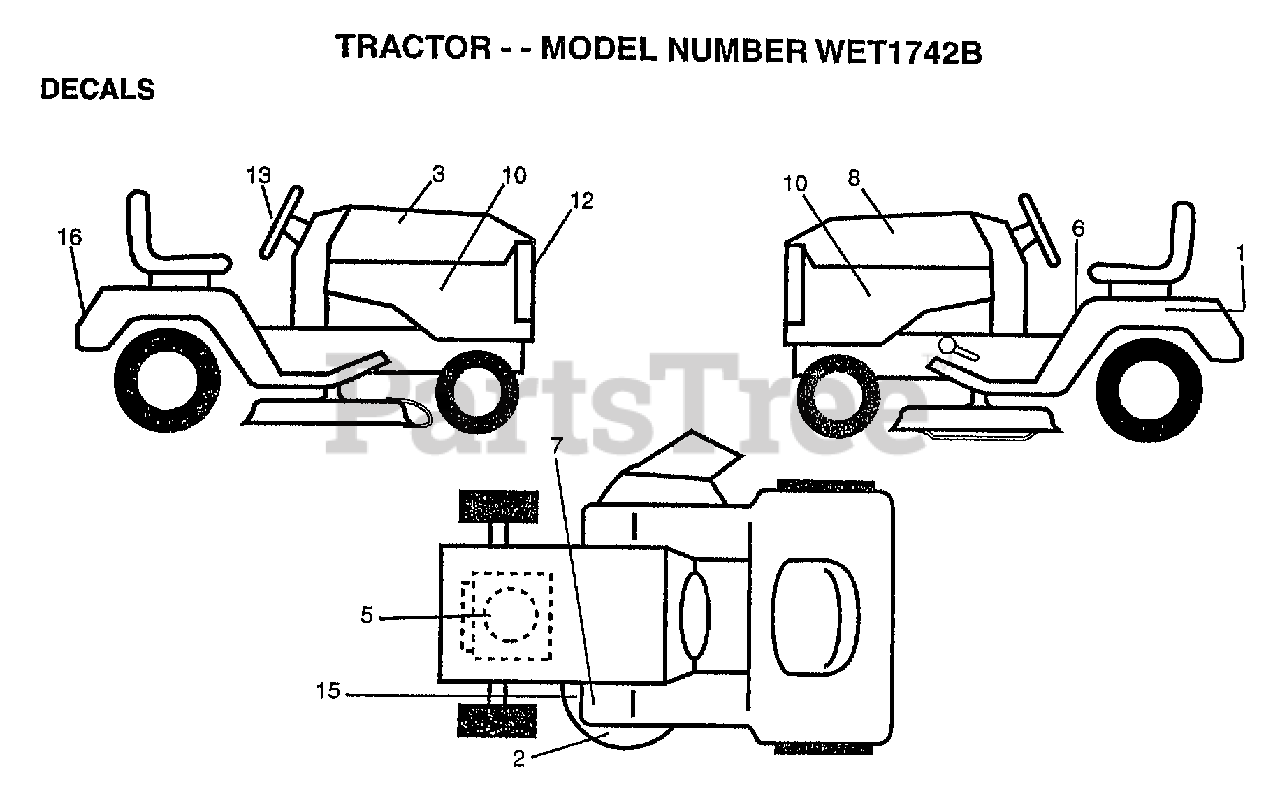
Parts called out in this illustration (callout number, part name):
1	DECAL.BATRY.3-3908
3	DECAL HOOD RH
6	"DECAL DANGER,FEND"
8	DECAL HOOD LH
10	DECAL PANEL SD
12	"DECAL GRILLE,LENS"
13	"DECAL INS,STRG WH"
15	DECAL
16	DECAL-FENDER
19	"DECAL DASH,OPER."
